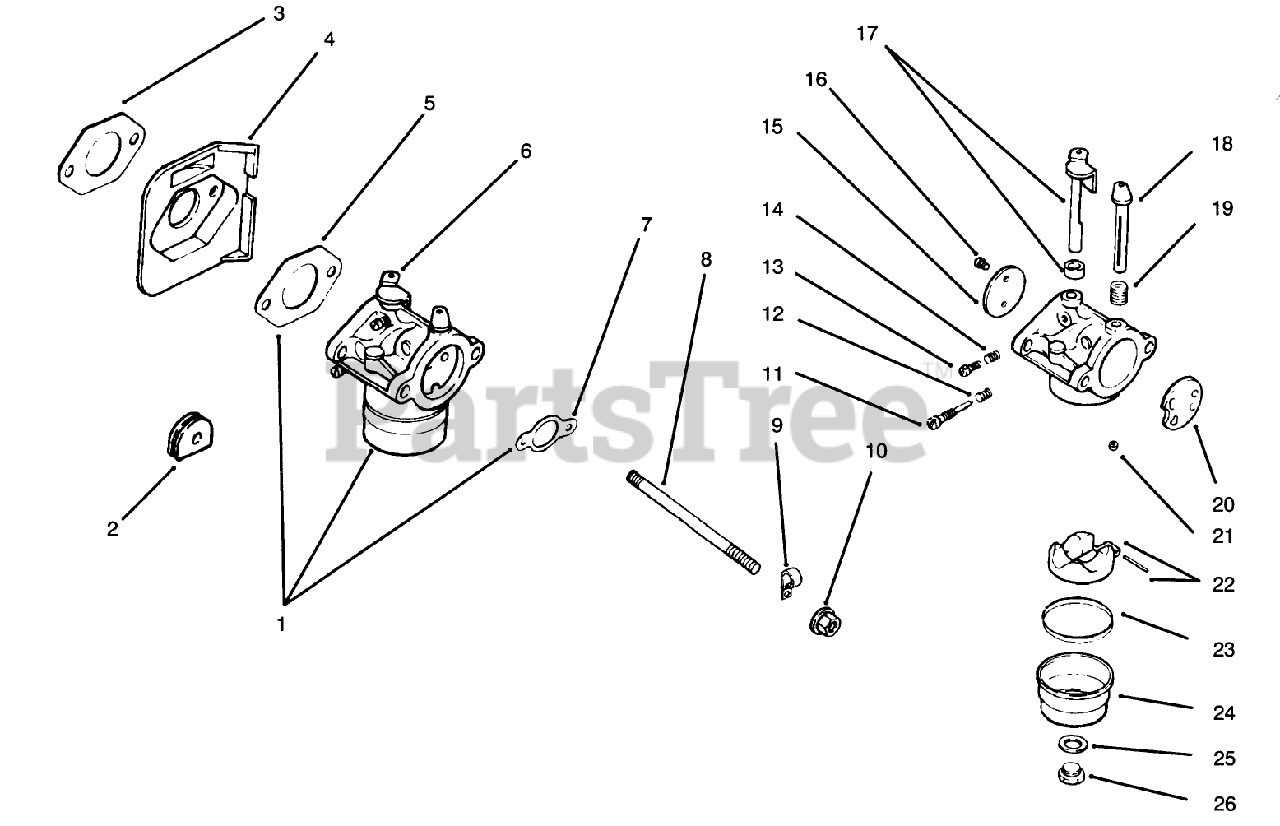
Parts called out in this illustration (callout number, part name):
1	Kit-Carb INCL 4/6/21 -36 (Only On: 72042,72043,72062,72063)
2	Grommet (Only On: 72042, 72063, 72062, 72043)
3	Gasket-Carburetor (Only On: 72042, 72063, 72062, 72043)
4	Deflector-Heat (Only On: 72042,72043,72062,72063)
5	Carburetor Assembly (Incl Ref. #11-26)
6	Gasket-Carburetor (Only On: 72042, 72063, 72062, 72043)
7	Gasket-Air Cleaner (Only On: 72042, 72043, 72062, 72063)
8	Stud M6x1.0x110 (Only On: 72042,72043,72062,72063)
11	Needle-Idle Fuel Adjust (Only On: 72042, 72063, 72062, 72043)
12	Spring-Idle Fuel (Only On: 72042, 72063, 72062, 72043)
13	Screw-Idle Speed Adjust (Only On: 72042,72043,72062,72063)
14	Spring-Idle Fuel (Only On: 72042, 72063, 72062, 72043)
15	Plate-Throttle (Only On: 72042,72043,72062,72063)
16	Screw-Throttle Plate (Only On: 72042,72043,72062,72063)
17	Shaft-W/Lever Seal (Only On: 72042, 72063, 72062, 72043)
18	Shaft-Choke (Only On: 72042. 72063, 72062, 72043)
19	Spring-Choke Return (Only On: 72042,72063, 72062, 72043)
20	Plate-Choke (Only On: 72042, 72063, 72062, 72043)
21	Jet-Main
22	Kit-Float (Only On: 72042,72043,72062,72063)
23	Gasket-Bowl (Only On: 72042,72043,72062,72063)
24	Bowl-Fuel (Only On: 72042, 72063, 72062, 72043)
25	Gasket-Bowl Screw (Only On: 72042, 72063, 72062, 72043)
26	Screw-Fuel Bowl (Only On: 72042, 72063,72062, 72043)
